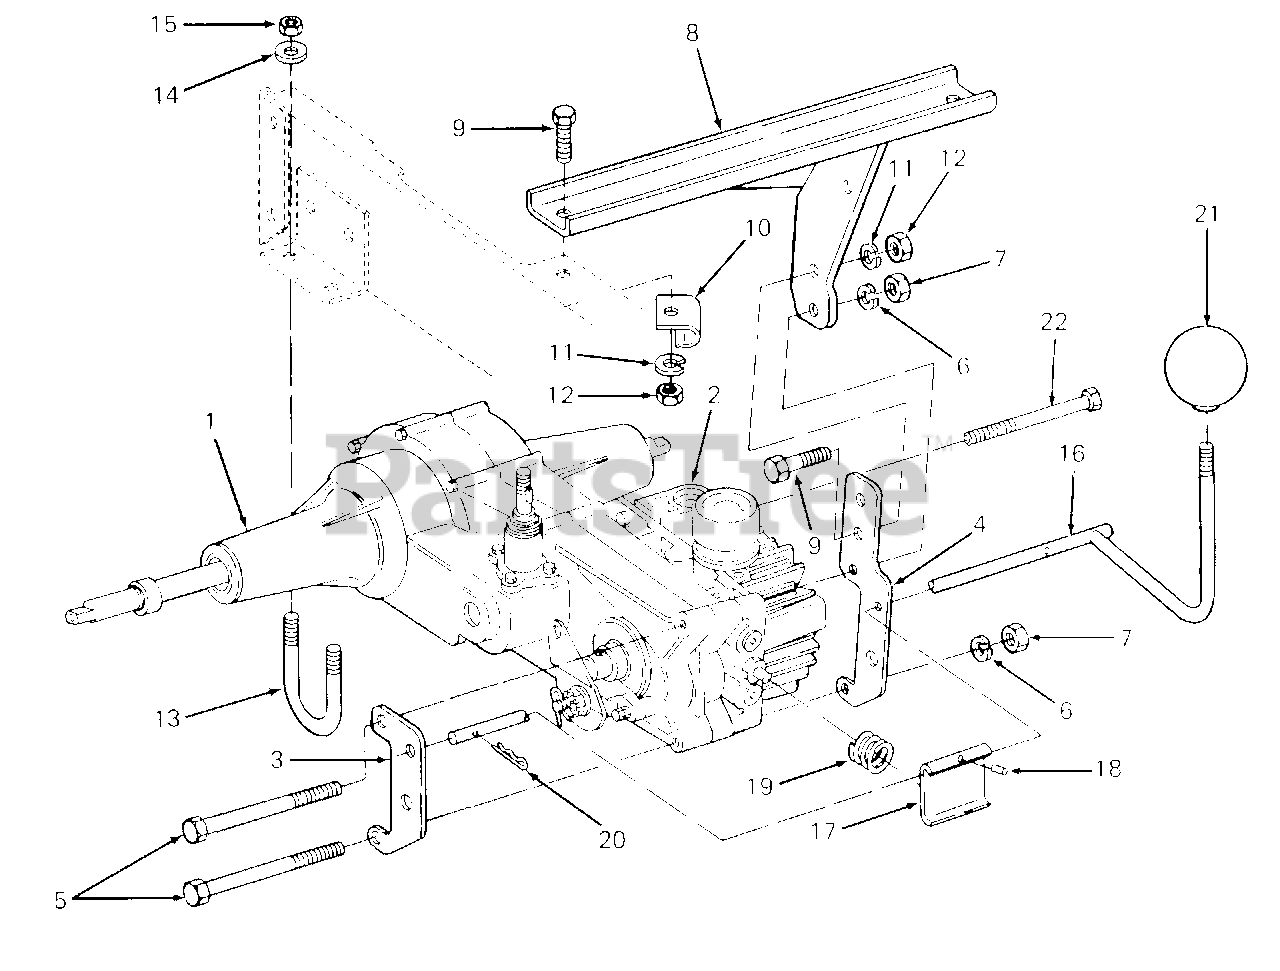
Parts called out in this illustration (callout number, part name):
1	Transaxle
2	Pump, Hydro
3	Bracket, Transmission Dump Valve
4	Bracket, Transmission Dump Valve Torque
5	Screw, Hex Cap, 5/16-18 X 4.5 Lg GR5
6	Washer, Lock, 5/16
7	Nut, Hex, 5/16-18 GR5
10	Clip, Cable
11	Washer, Lock, 3/8
12	Nut, Hex, 3/8-16 GR5
13	U-Bolt, 5/16-18 X 1.75 Lg
14	Washer, Bell, .345 X .88 X .060 Thk
15	Nut, Hex Center Lock, 5/16-18 GR5
16	Rod, Dump Valve
17	Lever, Dump Valve
18	Pin, Spiral Spring, 1/8 Dia X .75 Lg
19	Spring, Compression
20	Pin, Internal Cotter
21	Knob, Ball, 1/4-20 Trd
22	Bolt, Hex Patch, 5/16-18 X 4.5 Lg GR5
